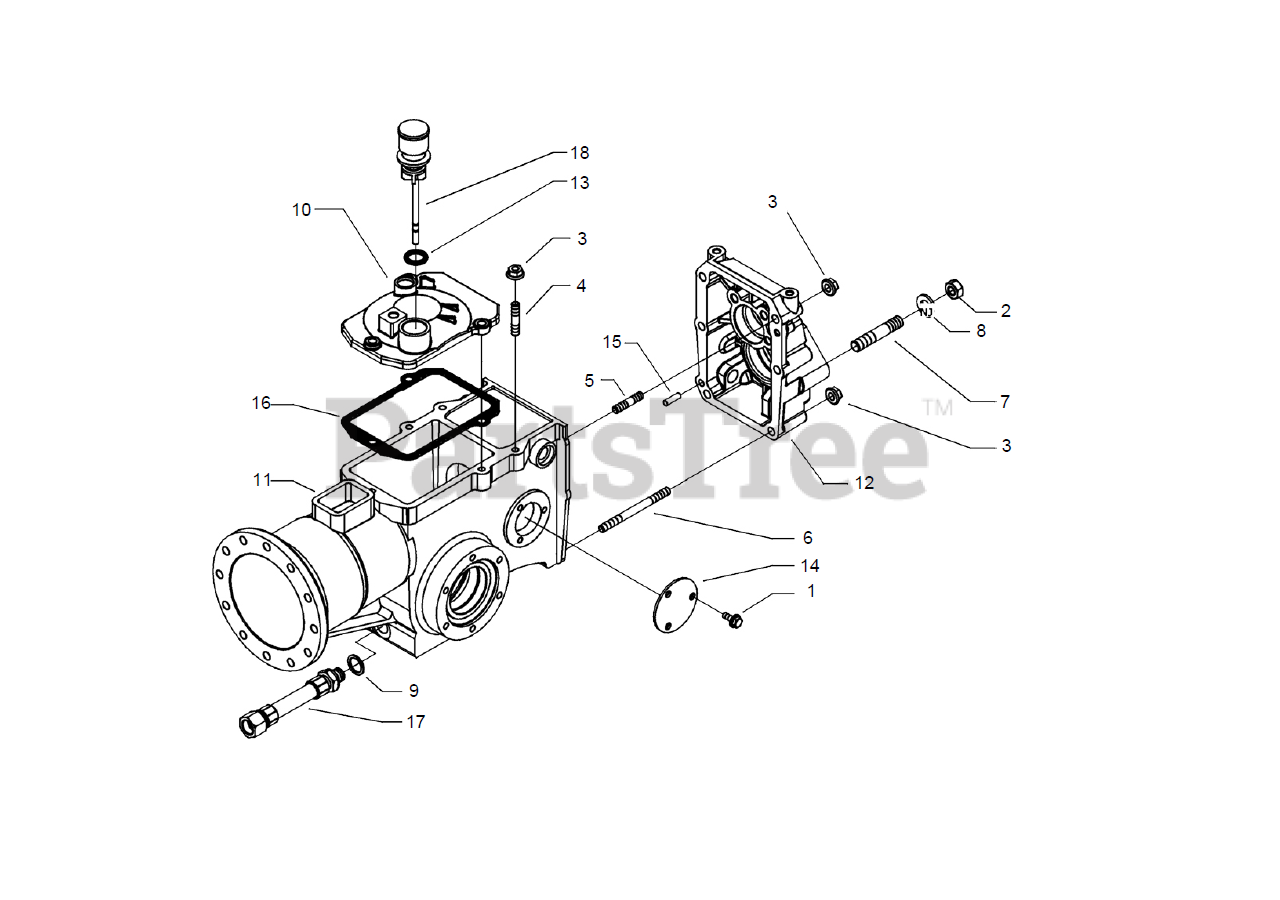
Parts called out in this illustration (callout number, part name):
1	SCREW
2	NUT M12X1.25 UNI 5587-6S
3	LOCKNUT M8, FLANGED
4	STUD M8X38X14X20 GRADE 8
5	STUD M8X56X20X12 GRADE 8
6	STUD M8X70X16X16 GRADE 8
7	STUD M64X12X1.25X26X12 GRADE 8
8	WASHER, TAPERED M13X24X3
9	COPPER WASHER 16.7X22X1.5 MM
10	COVER, GEARBOX
11	BOX CASING
12	REAR COVER
13	RING, RUBBER
14	COVER, SIDE
15	PIN, CYLINDRICAL D 6X18
16	GASKET, COVER
18	DIP STICK
